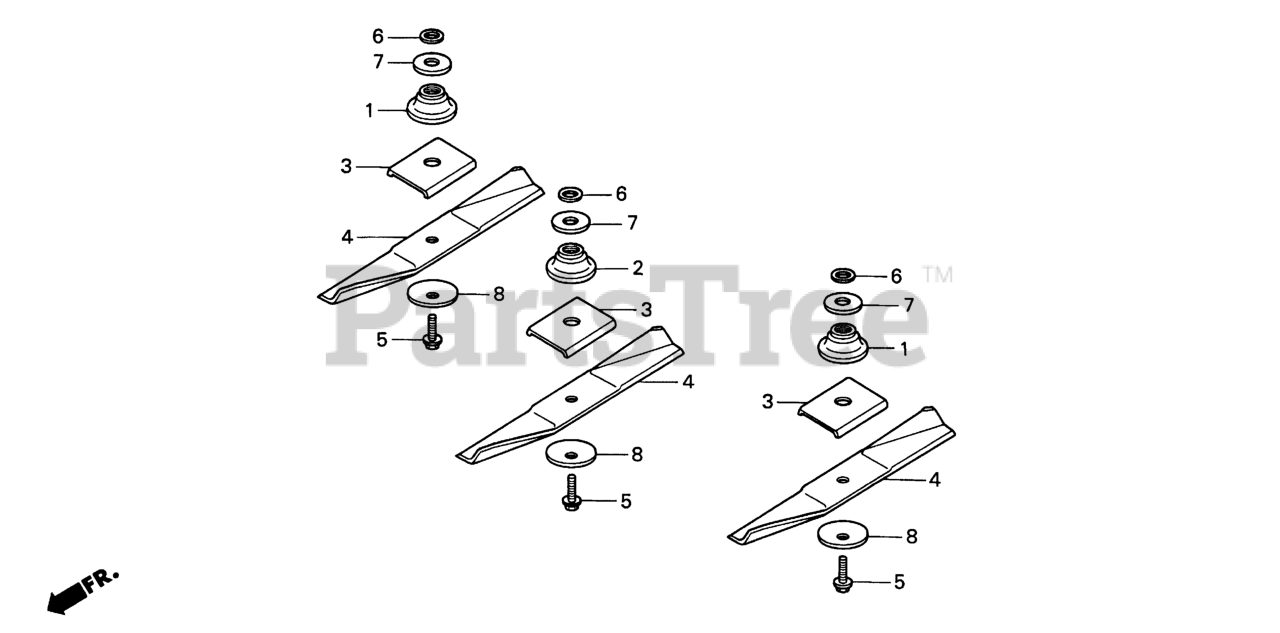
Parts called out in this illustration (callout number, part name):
1	HOLDER, BLADE
2	HOLDER, BLADE
3	HOLDER, BLADE (B)
4	BLADE, ROTARY
5	BOLT, BLADE HOLDER (10X28)
6	WASHER, THRUST (20MM)
7	WASHER, BLADE HOLDER
8	WASHER, BLADE
